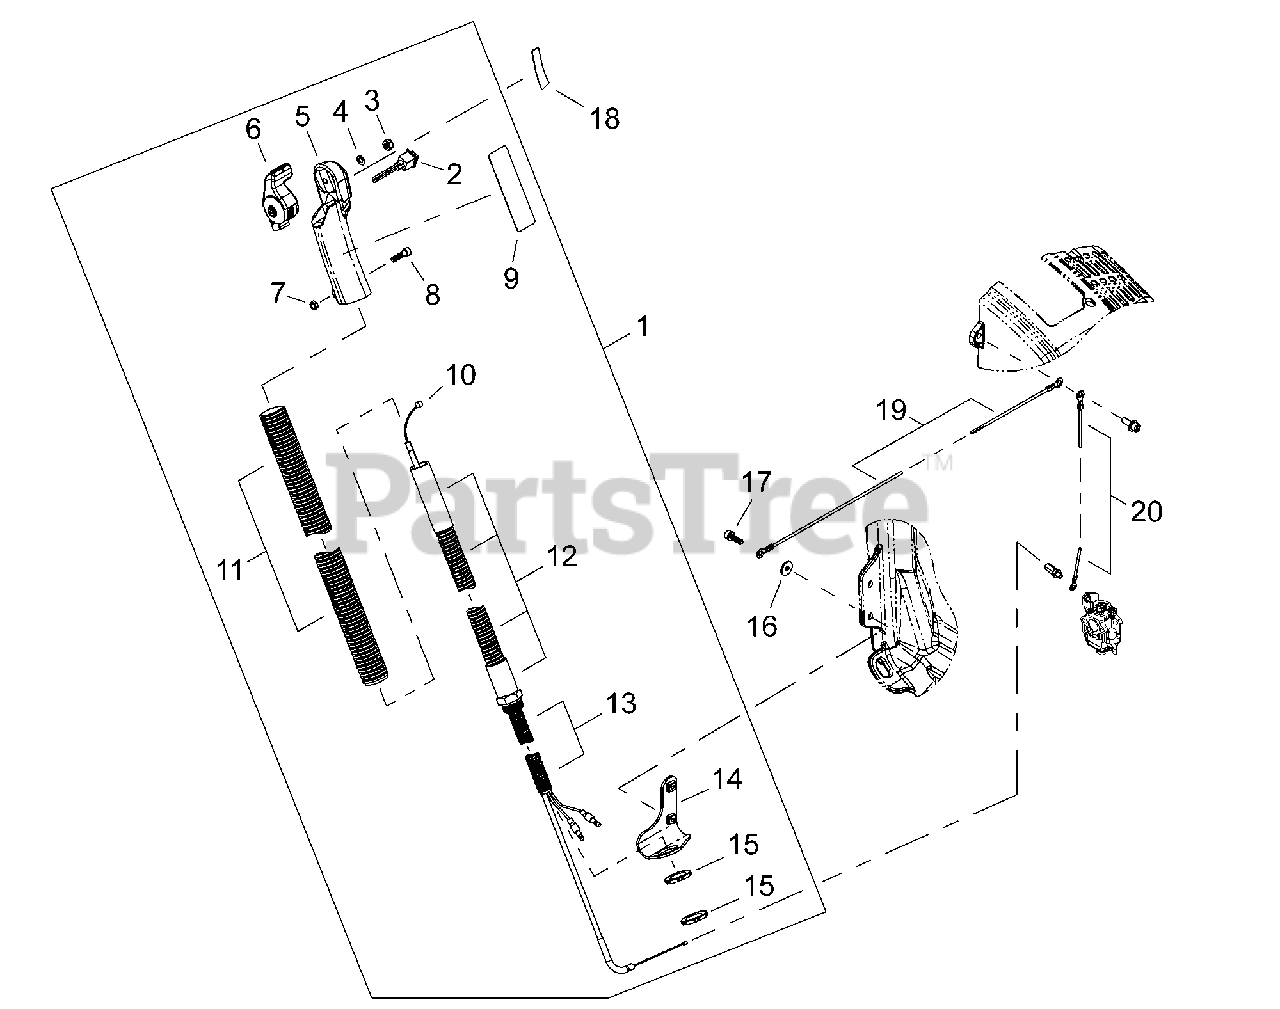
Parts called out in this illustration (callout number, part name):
1	THROTTLE CONTROL ASSY
2	IGNITION SWITCH ASSY
3	NUT - 5
4	WASHER - 5
5	GRIP
6	THROTTLE LEVER ASSY
7	NUT - 5
8	SCREW - 5X20
9	PLATE - GROUND
10	CABLE, THROTTLE
11	TUBE, PROTECTIVE
12	FLEX ARM
13	FLEX TUBE
14	BRACKET, MOUNTING
15	NUT - 21
16	COLLAR
17	SCREW - 5X18
18	LABEL - INSTRUCTION
19	LEAD - GROUND
20	LEAD - ANTI-STATIC - 110mm
